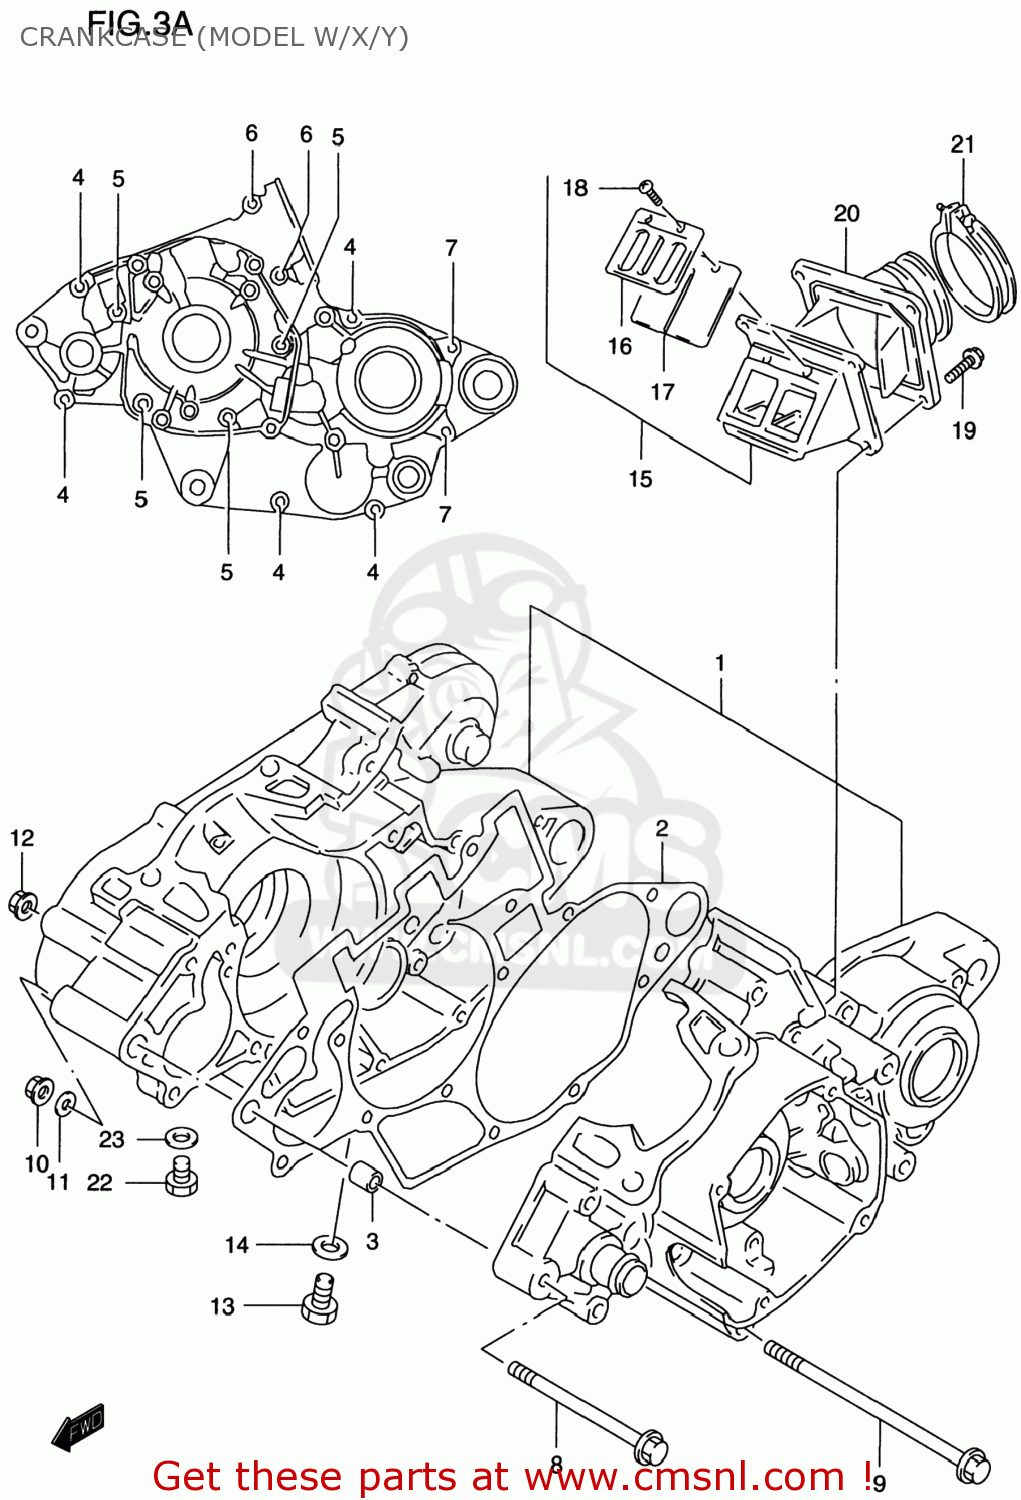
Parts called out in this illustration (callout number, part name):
1	CRANKCASE SET
2	GASKET,CRANKCASE
3	PIN(13X10.4X20)
4	BOLT
5	BOLT
6	BOLT
7	BOLT
8	BOLT(8X88)
9	BOLT(10X130)
10	NUT
11	WASHER
12	NUT
13	Bolt
14	GASKET(12.1X16.2X3.7) (NAS)
15	VALVE ASSY,REED
16	STOPPER,REED VALVE
17	VALVE,REED
18	SCREW
19	SCREW
20	PIPE,INTAKE
21	CLAMP
22	BOLT,DRAIN
23	GASKET 8.2X14X1 (NAS)
